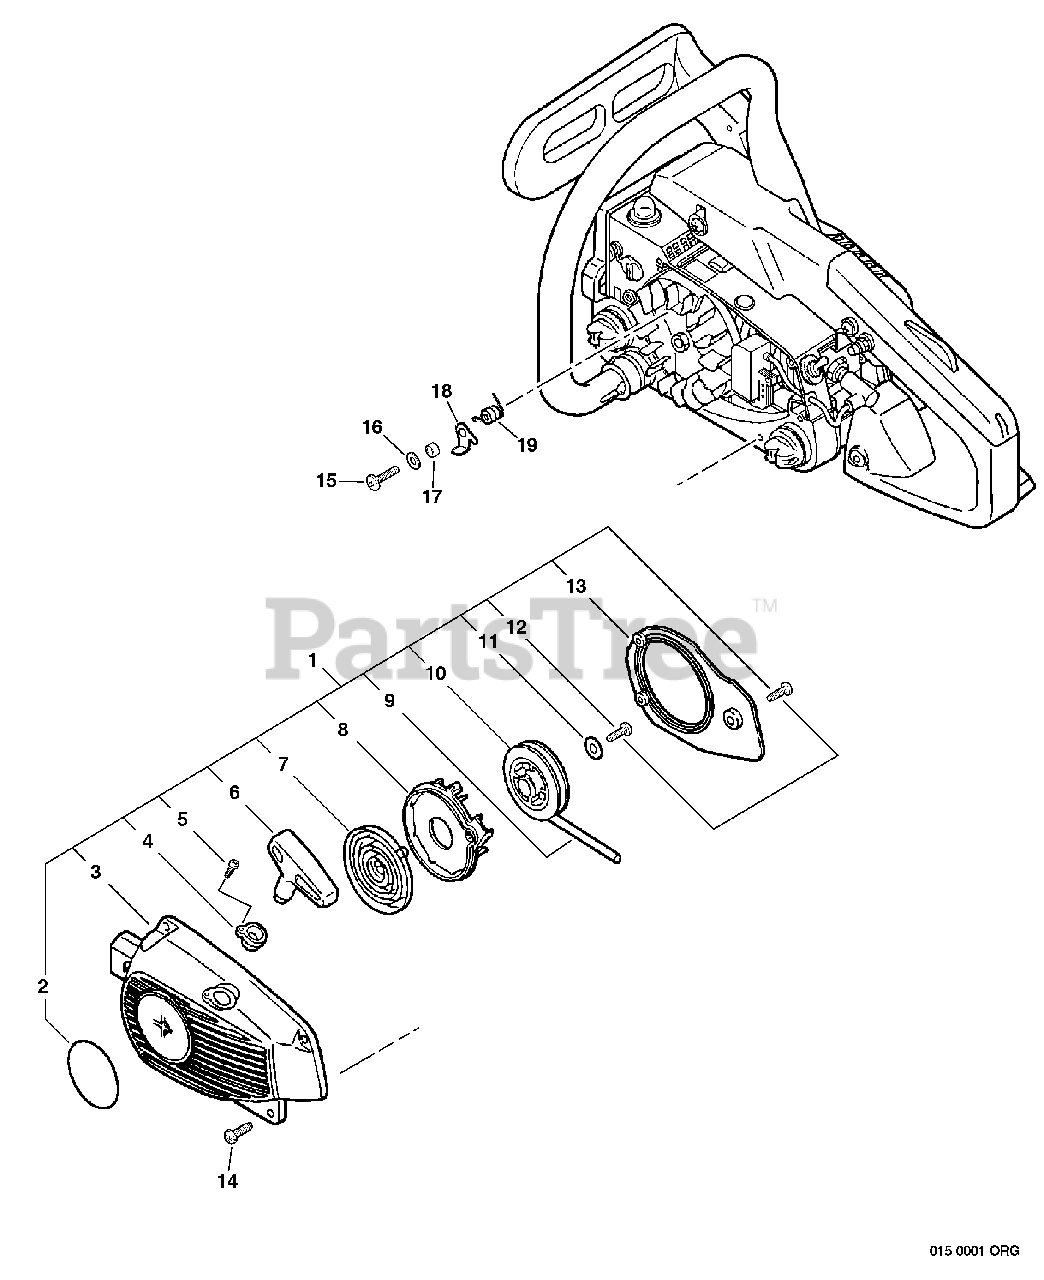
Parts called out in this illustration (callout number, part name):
1	STARTER ASSY
2	LABEL, ECHO
3	CASE, STARTER
4	GUIDE, ROPE
5	SCREW 3×14
6	GRIP, STARTER
7	SPRING, RECOIL
8	PLATE, STARTER
9	ROPE, STARTER 3.0×850
10	REEL, ROPE
11	WASHER 4.1×15.5×1T
12	SCREW 4×14
14	SCREW 4×16
15	SCREW 5×12
16	WASHER 5.5×12×0.8
17	SPACER 5.2×8×2.1
18	PAWL, STARTER
19	SPRING, TORSION
